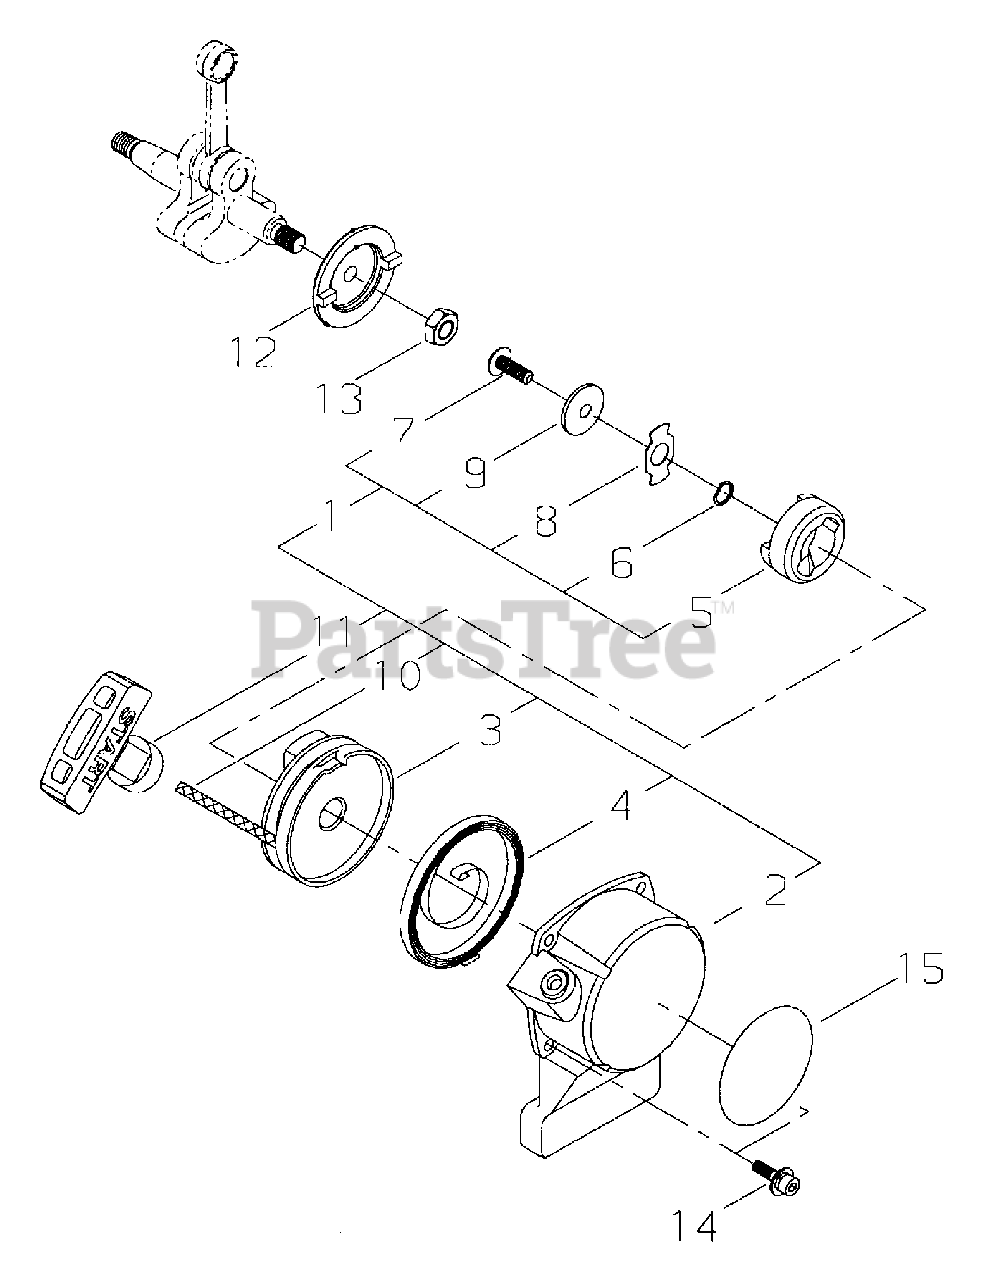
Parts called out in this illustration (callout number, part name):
1	STARTER ASSY, RECOIL
2	CASE, RECOIL STARTER
3	REEL, ROPE
4	SPRING, RECOIL
5	PAWL, STARTER
6	WASHER, WAVE
7	SCREW 5 MM
8	RETAINER
9	WASHER 5 MM
10	ROPE, STARTER
11	GRIP, STARTER
12	PULLEY, STARTER
13	NUT M8×1
14	BOLT M4×16
15	LABEL, RECOIL C4
